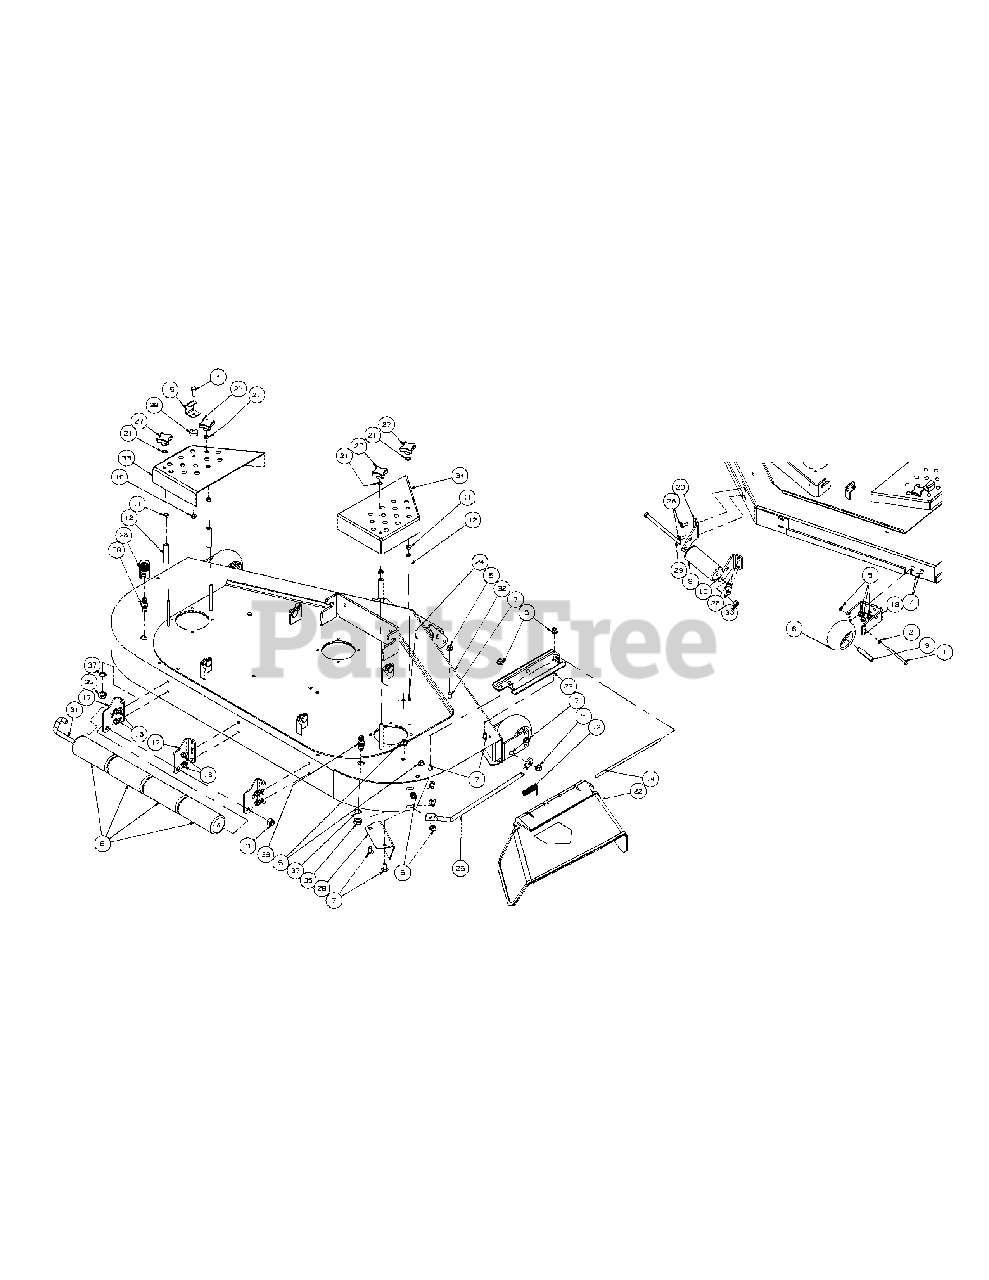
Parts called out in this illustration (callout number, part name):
1	Hex Cap Screw, 3/8-16, 3.75
3	Hex Nut, 1/2-13, Insert Lock
4	Hex Cap Screw, 5/16-18, 1.00
5	Hex Nut, 3/8-16 Flange Lock
6	Complete Wheel, 5.00 Dia
7	Carriage Bolt 3/8-16 x .75
8	Front Roller
9	Wheel Spacer
10	Hex Nut, 5/16-18 Flange Lock
11	Nut, 3/8-16, Jam
12	Spacer, .39 ID x .625 OD x 2.75
13	Torsion Spring
14	Chute Deflector Rod
15	Stop Bracket
16	Self Tapping Screw, 5/16-18 x 1/2
17	Fabricted Deck Roller Mount Bracket
18	Front Anti-Scalp Wheel Mount Bracket
19	Left Hand Front Roller Mount Bracket
20	Right Hand Front Roller Mount Bracket
21	External Washer, 3/8
22	Deflector Chute
23	Deflector Chute Bracket
24	Carriage Bolt, 3/8-16 x 4.00
25	Fabricated Deck Finger Guard
26	Self Tapping Screw, 3/8-16 x 0.875
27	Plastic Knob
28	Fabricated Deck, Chute Bracket
29	Hex Cap Screw, 1/2-20 x 7.50
30	Lock Nut, Nylon Insert, 1/2-20
31	J-Hook w/ Threaded Roller
32	54 Fabricated Deck Assembly
33	Belt Cover, LH
34	Belt Cover, RH
35	Hex Nut, M16-1.5
36	Water Nozzle Adaptor
37	Lock Washer, 17 x 23.8 x 1.95
38	Deck Water Nozzle
39	Spacer .406 ID x 1.0 OD
